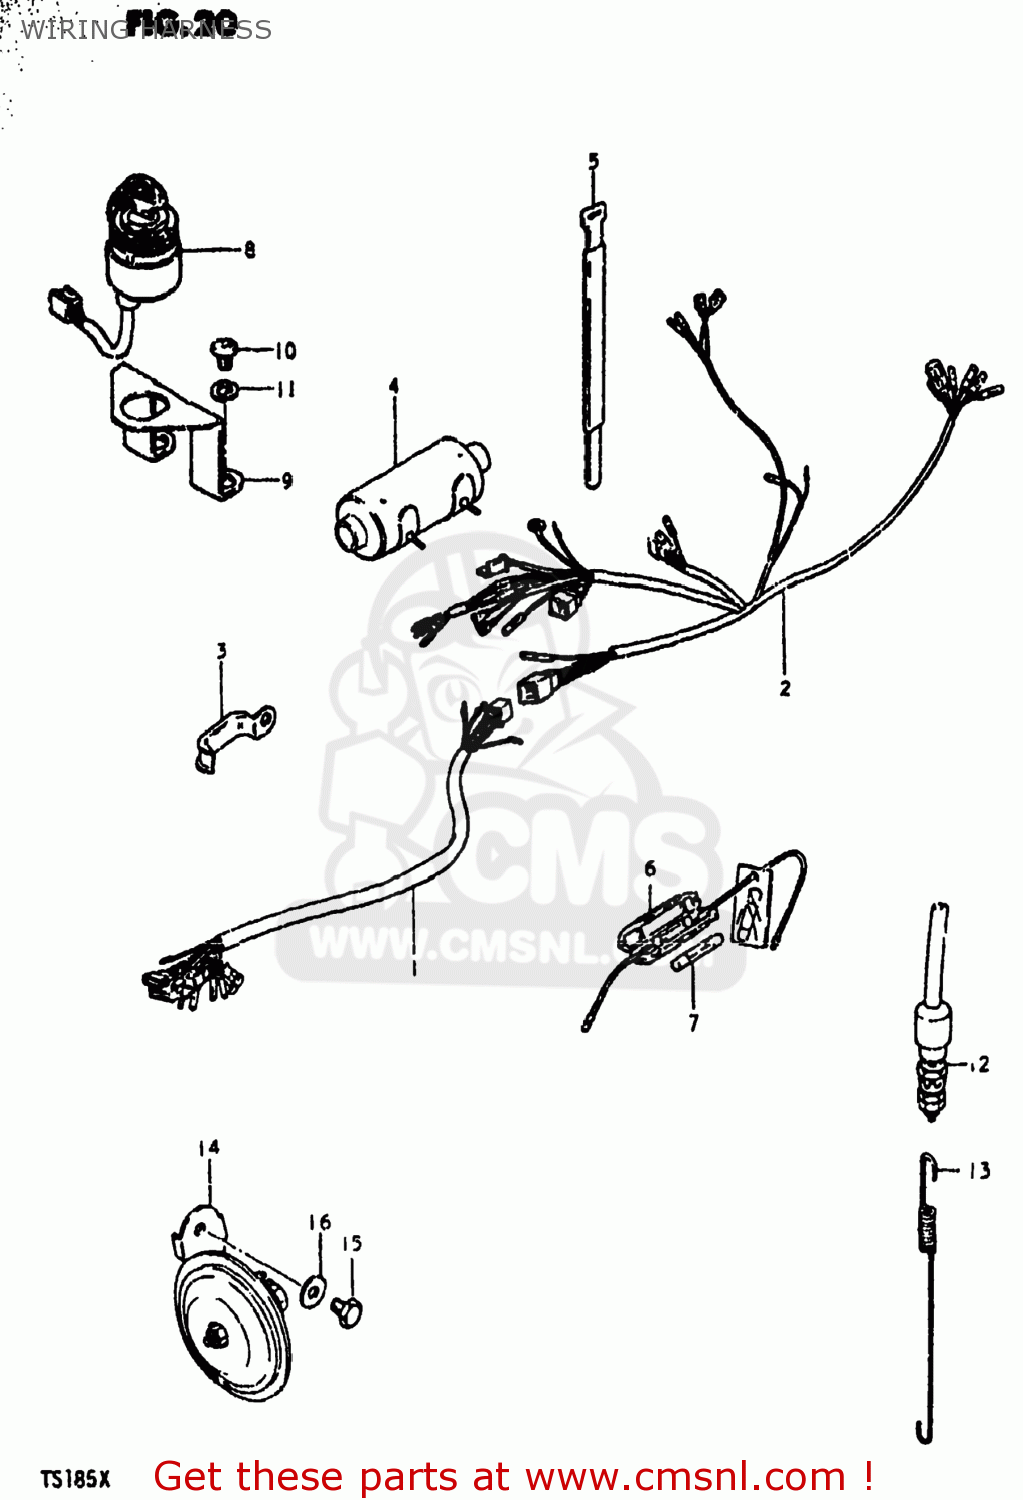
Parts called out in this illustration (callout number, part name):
1	HARNESS,WIRING
2	HARNESS,WIRING NO.2
3	CLAMP
4	BOOT,WIRING HARNESS
5	CLAMP
6	BOX ASSEMBLY,FUSE
7	FUSE(15A)
8	SWITCH ASSEMBLY,IGNITION
9	BRACKET,IGNITION SWITCH
10	SCREW
11	LOCK WASHER
12	SWITCH ASSEMBLY,STOP LAMP
13	SPRING
14	HORN ASSEMBLY
15	BOLT
16	WASHER
